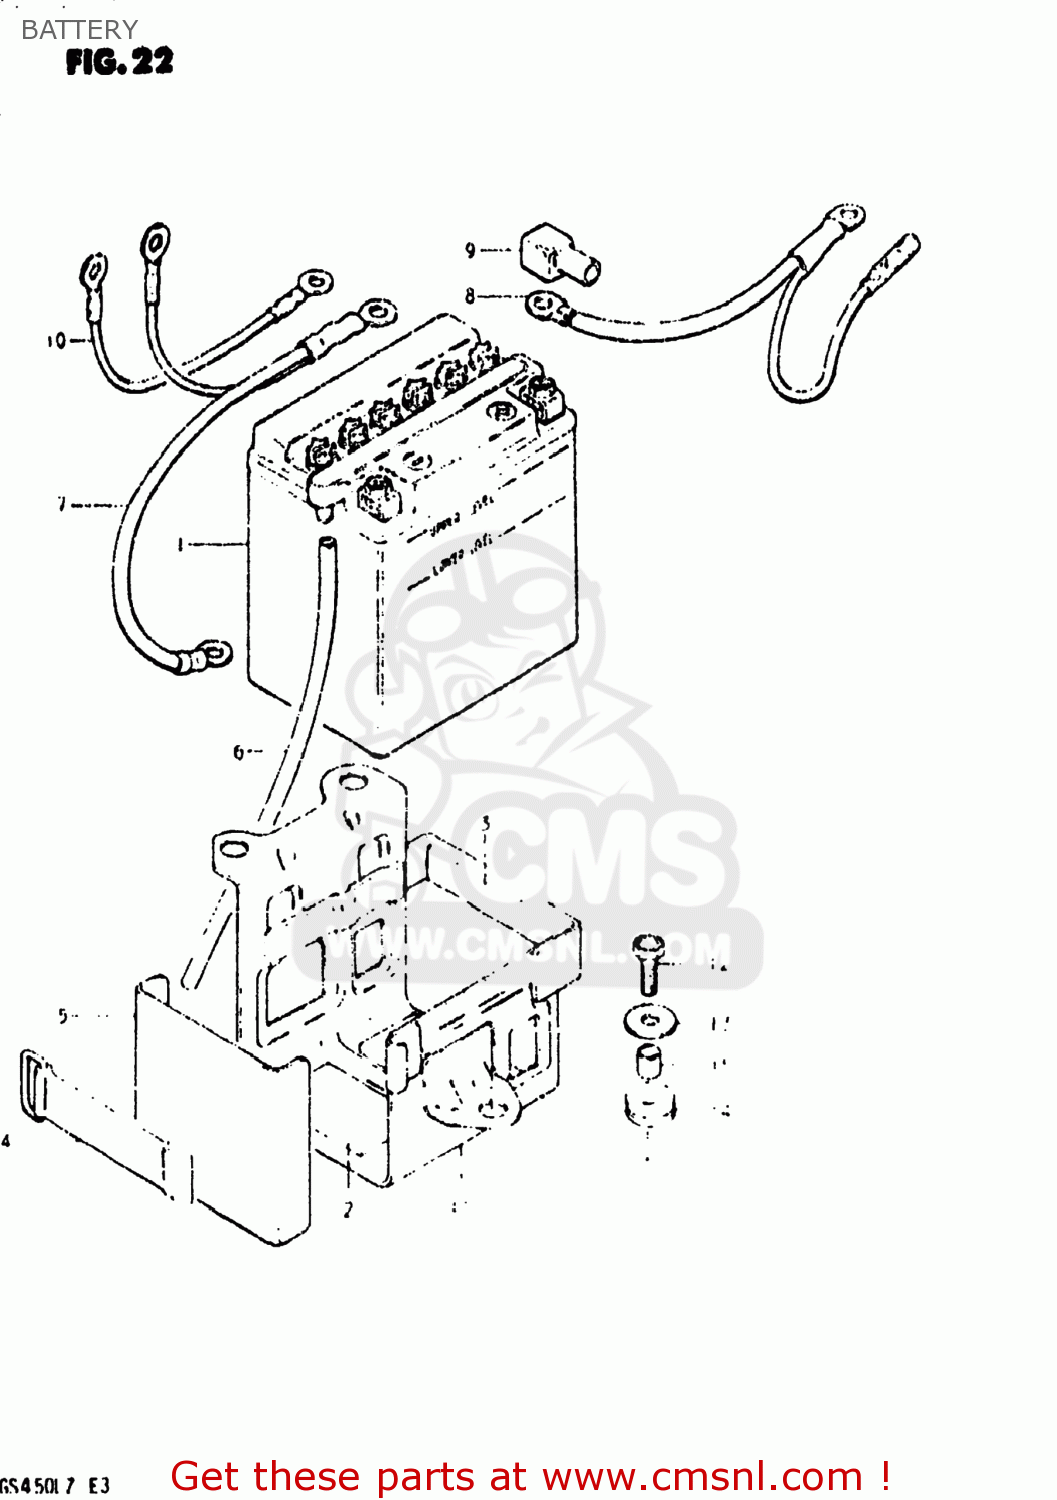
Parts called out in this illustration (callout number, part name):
1	BATTERY ASSY (12V)
2	CUSHION,BATTERY
3	PROTECTOR,20X9
4	BAND
5	COVER,BATTERY
6	HOSE,BATTERY EXHAUST
7	CORD,BATTERY MINUS
8	WIRE,BATTERY PLUS
9	CAP,TERMINAL
10	WIRE
11	HOLDER,BATTERY
12	BOLT
13	WASHER
14	CUSHION
15	SPACER (6.1X9X9)
